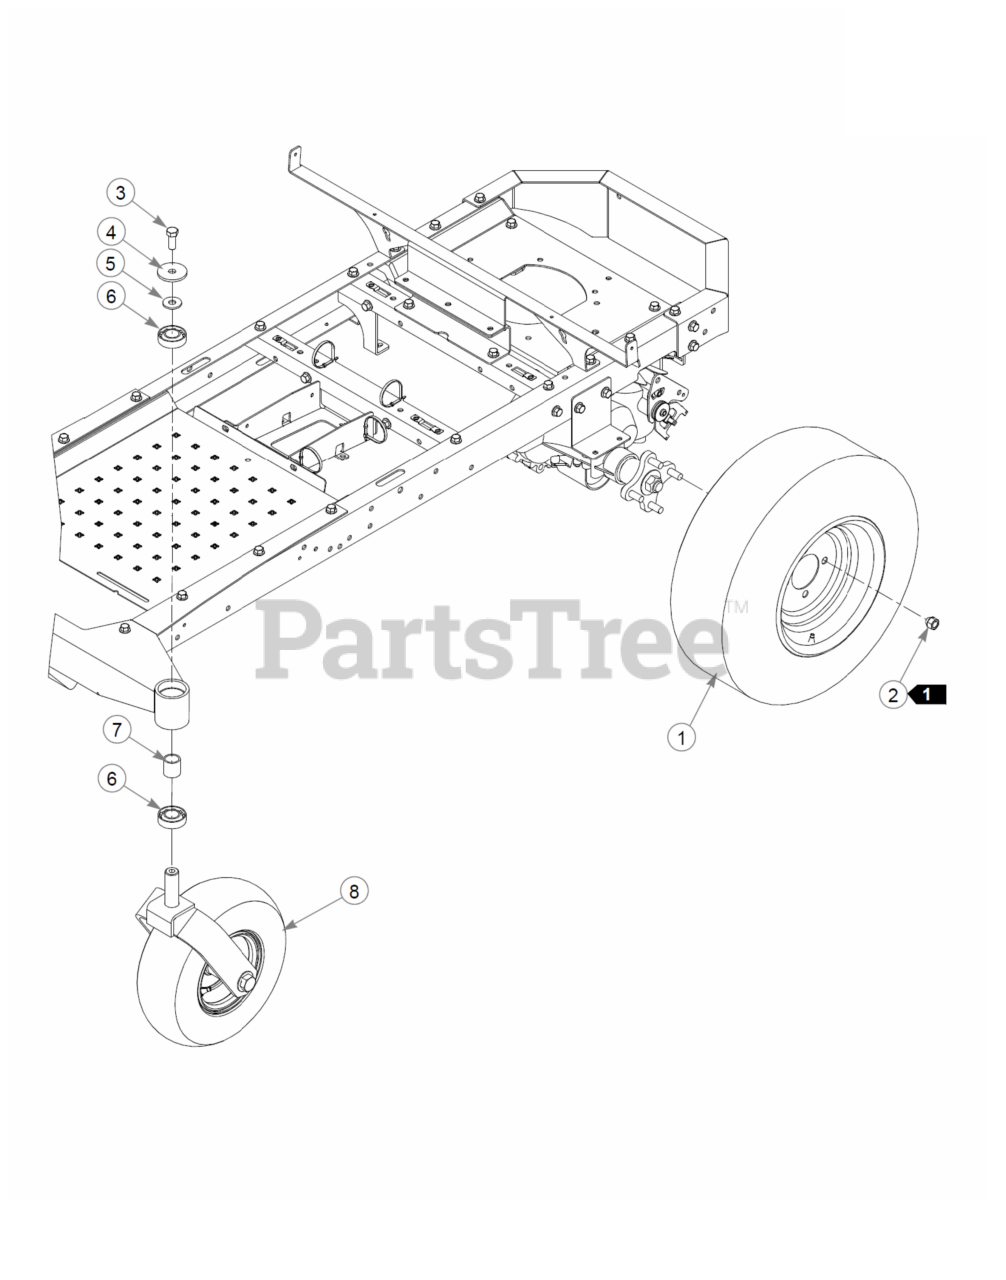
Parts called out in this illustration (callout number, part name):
1	TIR/WHL 20X12.00-10 SLV
1	TIR/WHL 20X8.00-10 SLV
2	WHEEL NUT
3	CS .500-13X1.25 HX G5 ZN
4	FW .510X2.15X.19 ZN
5	ASSEMBLY CHUTE & GEAR BLK
